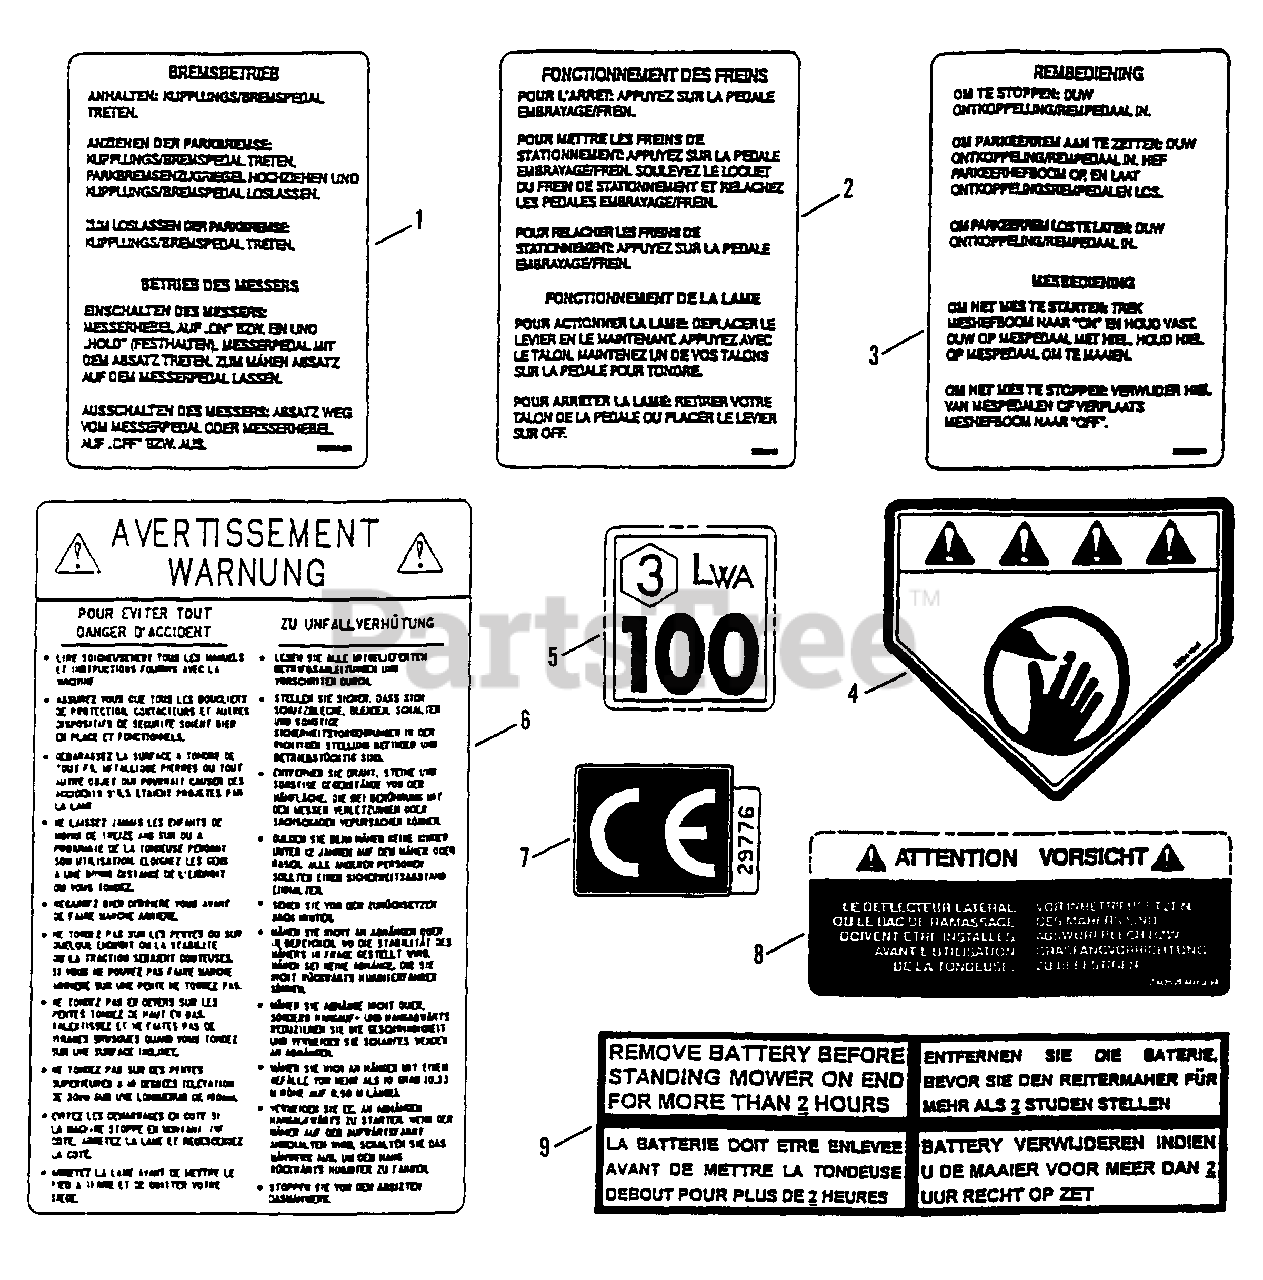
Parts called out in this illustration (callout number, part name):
1	DECAL,
2	DECAL,
3	DECAL,
4	DECAL,
5	DECAL,
6	DECAL,
7	DECAL,
8	DECAL,
9	DECAL,
